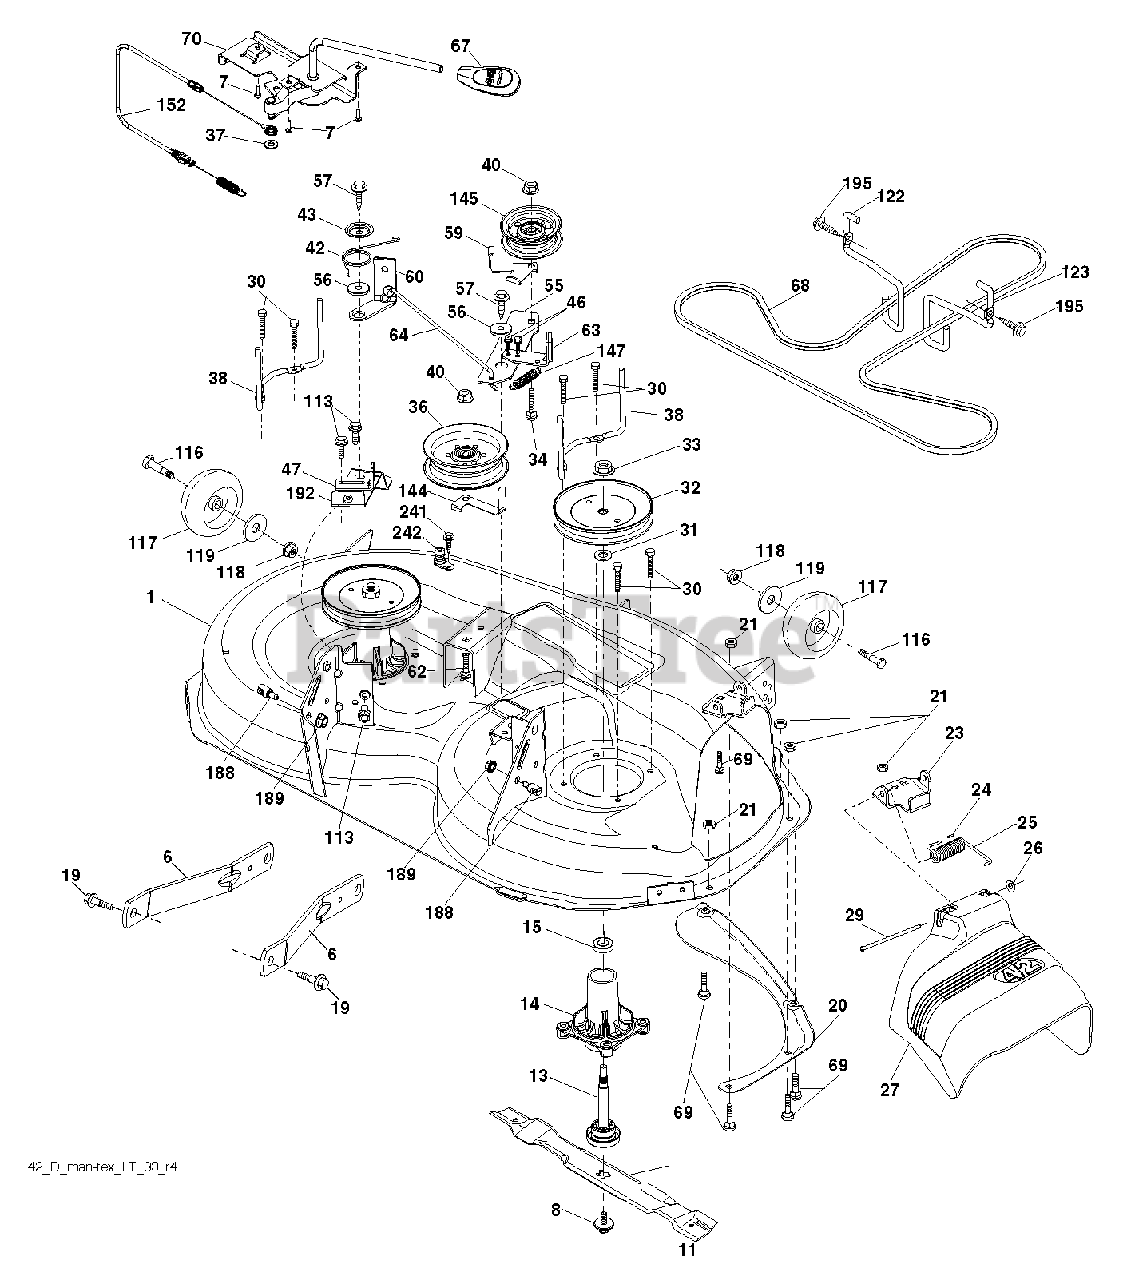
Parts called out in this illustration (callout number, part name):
1	DECK.WELDMENT.42"
6	ARM.SUSPENSION.MOWER.R
7	SCREW.#10 X 0.750.BOS THREAD
8	BOLT.WASHER.ASM.7/16-2
11	42" HI-LIFT BLADE
13	SHAFT.ASM.MDRL.N/GREASE.38
14	HOUSING MANDREL
19	BOLT.SHOULDER
20	BAFFLE.VORTEX
21	LOCKNUT
23	BRKT.DEFLECTOR.38"2005+
24	CAP-SLEEVE LT
25	SPRING.TORSION.DEFLECT
26	NUT PUSH M
27	SHIELD.DEFLECTOR.MOWER.42"BLAC
29	ROD.HINGE
30	SCREW, WASHER HEAD
31	WASHER.SPACER.MANDREL
32	PULLEY.MANDREL.5.438.PD
33	NUT.FLANGE.LOCK.TOP
34	BOLT.3/8-16X1.50
36	PULLEY.IDLER.2006
38	KEEPER.BELT.LH.MANDREL
40	NUT LOCK FLG 3/8-16 UNC
42	SPRING.TORSION.BRAKE
43	SRPING.TORSION.RETAINE
46	SCREW.1/4-20X5/8
47	BRKT.CLUTCH.CABLE
55	IDLER.ARM.42"
56	SPACER.RETAINER
57	SCREW 3/8-16X1
59	GUARD, BELT
60	ARM BRAKE MOWER
62	BOLT
63	ARM BRAKE MOWER
64	LINK BRAKE
67	HANDLE.CLUTCH.CABLE.LT
68	BELT.DECK.DRIVE.42"
69	BOLT
70	CLUTCH.ASM.MANUAL.LT.PRED
113	BOLT.5/16HEX.WHS.HD
117	WHEEL.GAGE.HALF.SPOKED
118	NUT LOCK FLG 3/8-16 UNC
119	WASHER
122	KEEPER BELT ENGINE LH
123	KEEPER BELT RH
144	KEEPER.BELT.MOWER
145	PULLEY.IDLER.48"PRIMARY
147	RETURN SPRING
152	CLUTCH CABLE
188	STUD.FASTNER.W/ANTI-ROTATE
189	NUT LOCK HEX FLANGE 5/16-18
192	BRKT.BRAKE.STAND.LH.
195	SCREW, 3/8-16X3/4
242	PORT.WASHOUT
